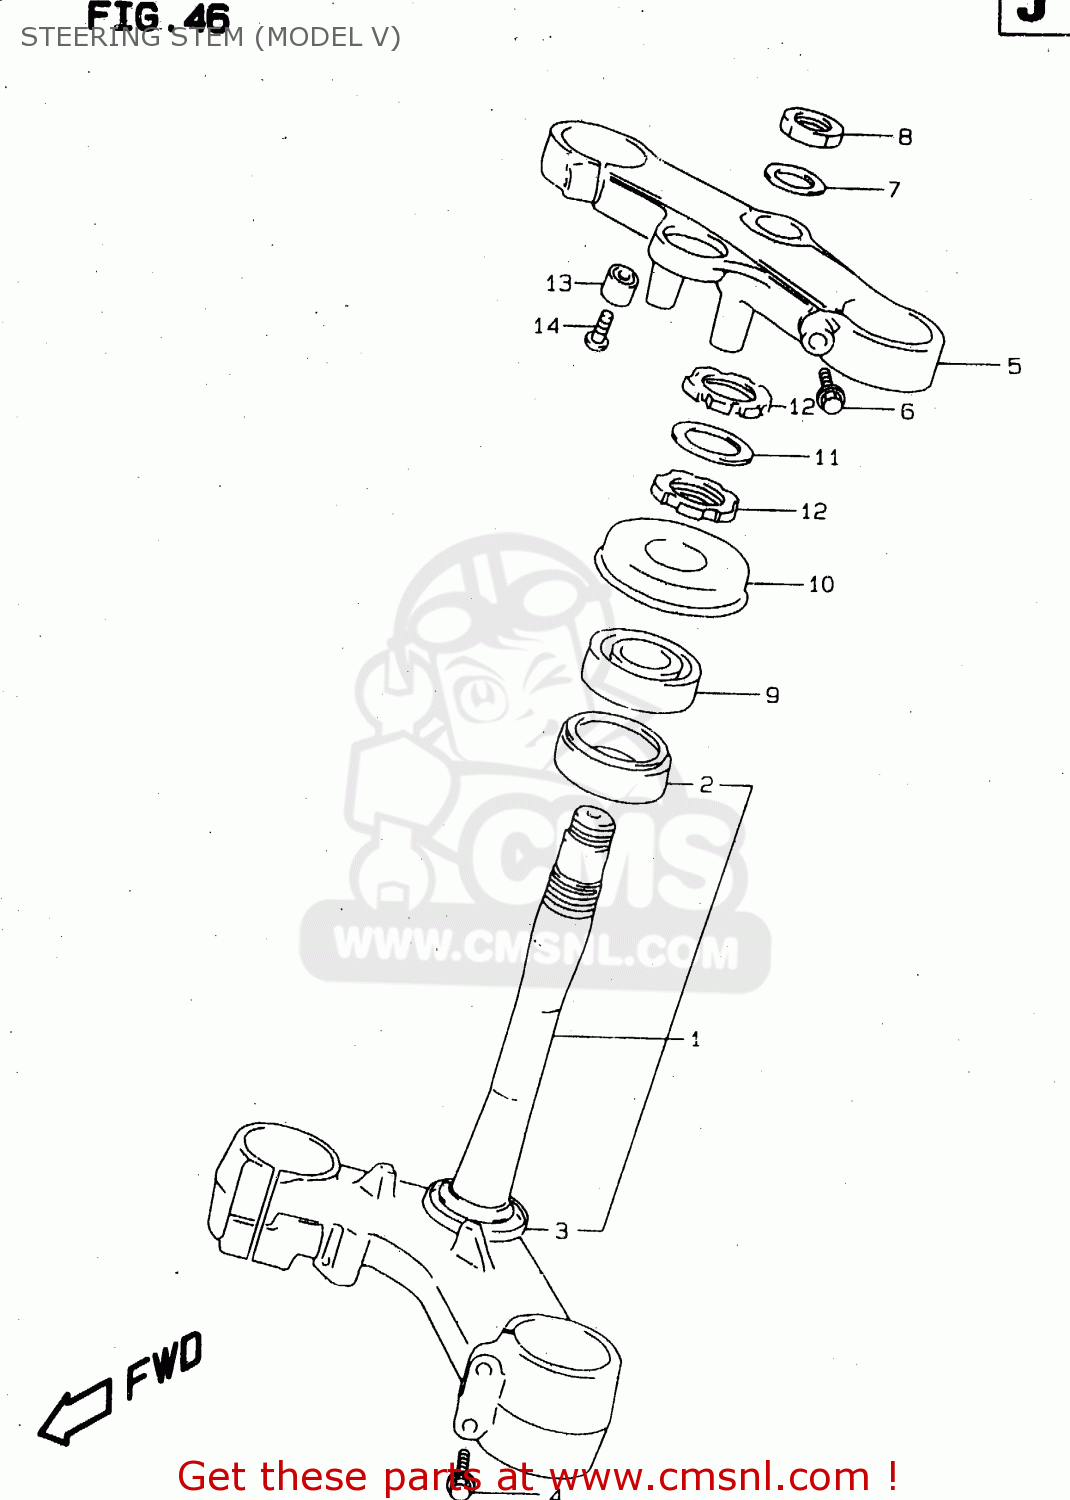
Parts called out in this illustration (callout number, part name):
1	STEM,STEERING
2	BEARING(30X55X17)
3	SEAL,STEERING LWR
4	BOLT
5	HEAD,STEERING STEM
6	BOLT
7	WASHER,STEERING DAMPER
8	NUT
9	BEARING(30X55X17)
10	SEAL,STEERING UPR DUST
11	WASHER,STEERING STEM
12	NUT,STEERING STEM
13	BALANCER,BRACKET UPR
14	SCREW
